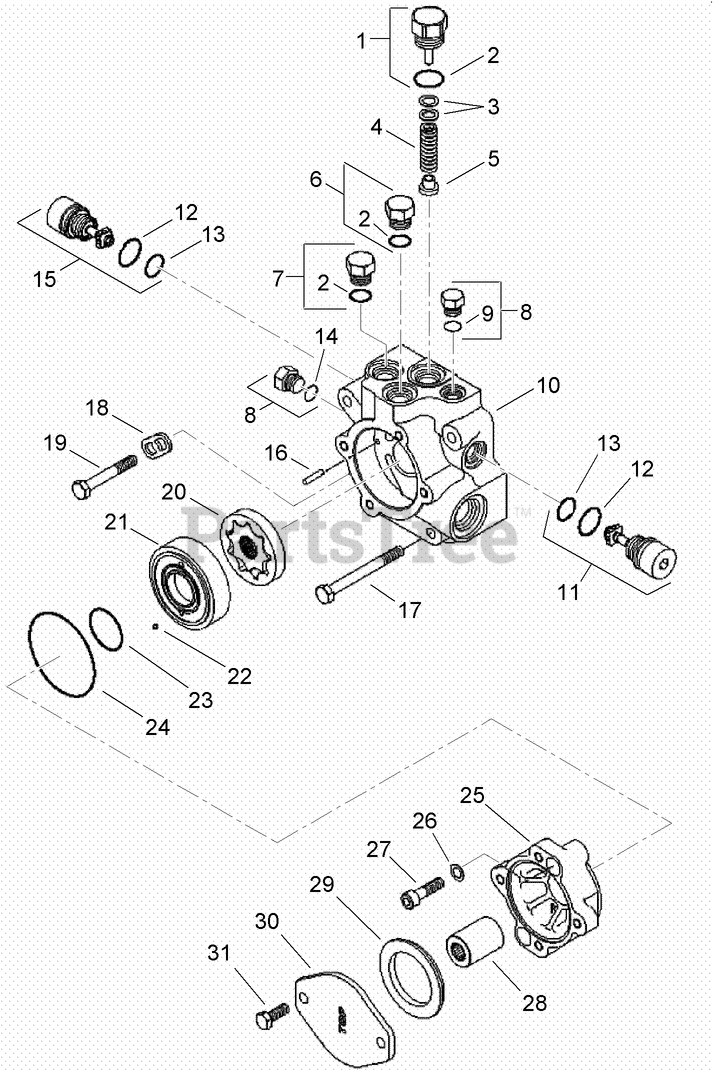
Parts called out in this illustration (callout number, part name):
2	O-RING
3	KIT - Charge Relief Shim
5	POPPET - Charge Rel
6	Plug
7	Plug
8	PLUG-Hex Hd, ORB 3/8
9	O-RING
10	CAP - Pump End
11	POPPET - Check Valve
12	O-RING - 3/4 x 1 Class 5
13	O-RING
14	O-RING
15	ASSEMBLY - Check Valve
17	BOLT - M10 x 80
18	BRACKET-Lifting
19	BOLT - M10 x 65
20	SET - Gear
21	SPACER - Gerotor
22	BALL - .187 in GR24
25	ADAPTER - A Flange
26	WASHER - Special
27	SCREW - M10 x 40
28	COUPLING
29	SEAL - A Pad
30	PLATE - Cover
31	SCREW-HH
